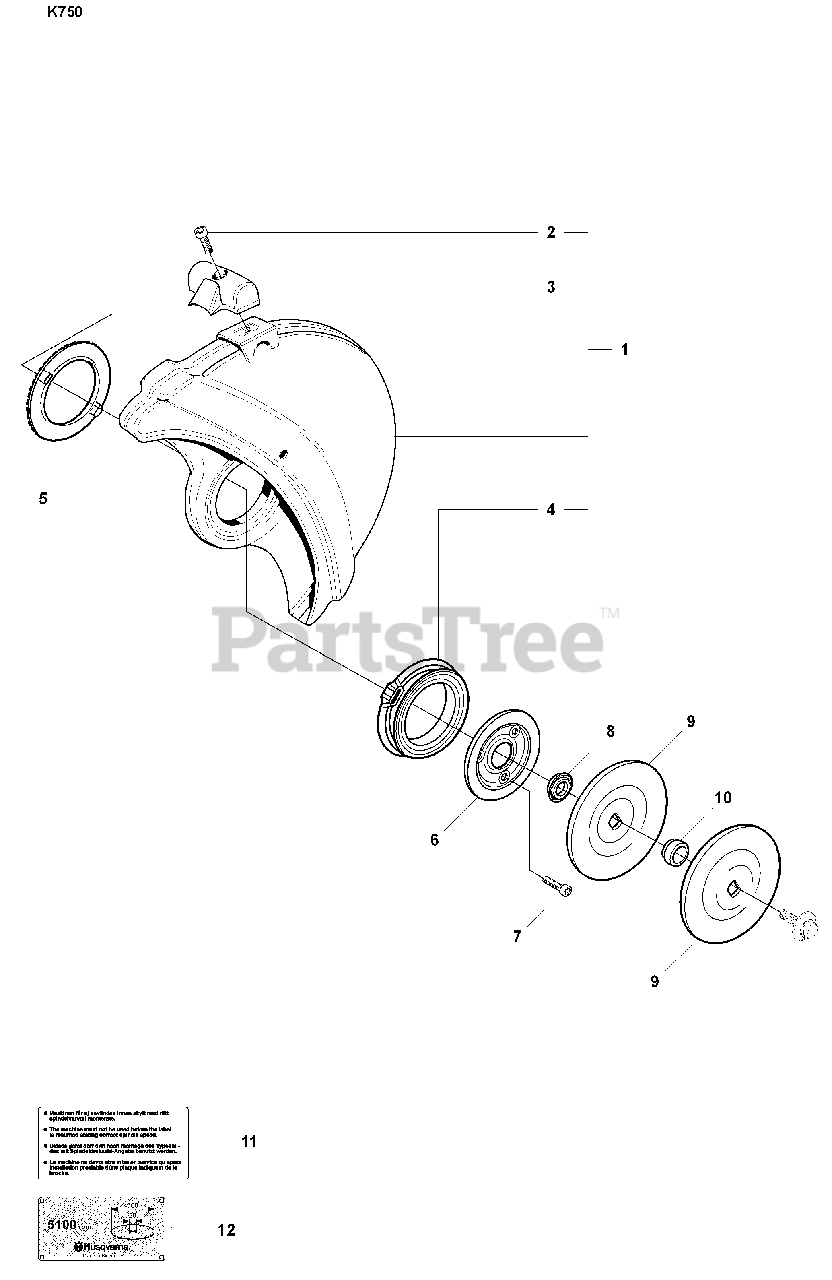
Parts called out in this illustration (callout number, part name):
1	WHEEL GUARD ASSY
2	SCREW
5	SCREEN PATTERN FLANG
8	SUPPORT FLANGE
9	WASHER
10	BUSHING
11	INFORMATION LABEL
12	LABEL
